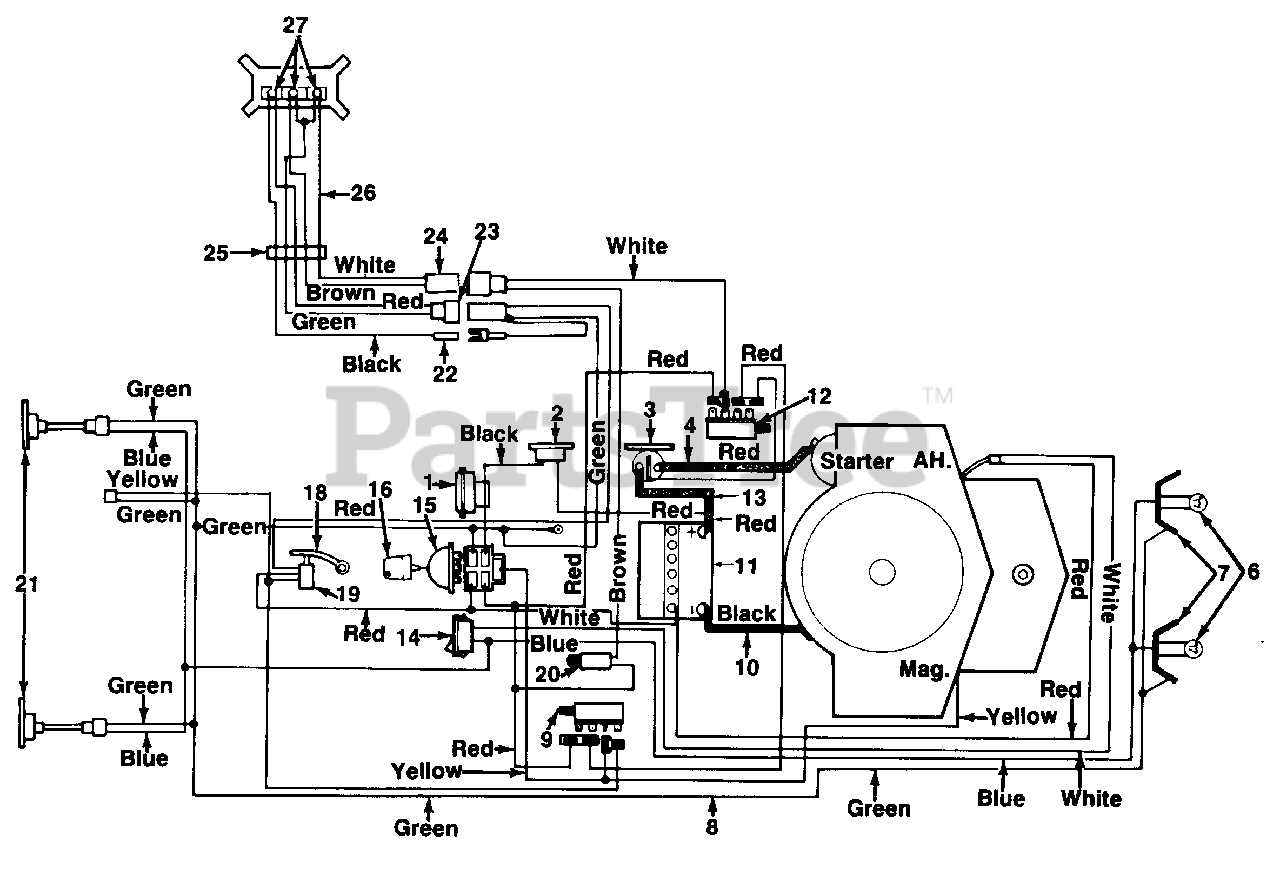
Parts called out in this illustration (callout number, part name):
1	Ammeter
2	Circuit Breaker
3	Solenoid
4	Wire
6	Bulb
7	Socket
8	Wire Harness
9	Safety Switch
10	6 Ga. Black Wire
11	Battery 12V
12	Safety Switch
14	Light Switch
15	Ignition Switch
16	Ignition Key
18	Spring Lever
19	Safety Switch
20	Safety Switch
21	Taillight
22	Connector
23	Connector
24	Connector
25	Clamp
26	Wire Harness
27	Bulb
